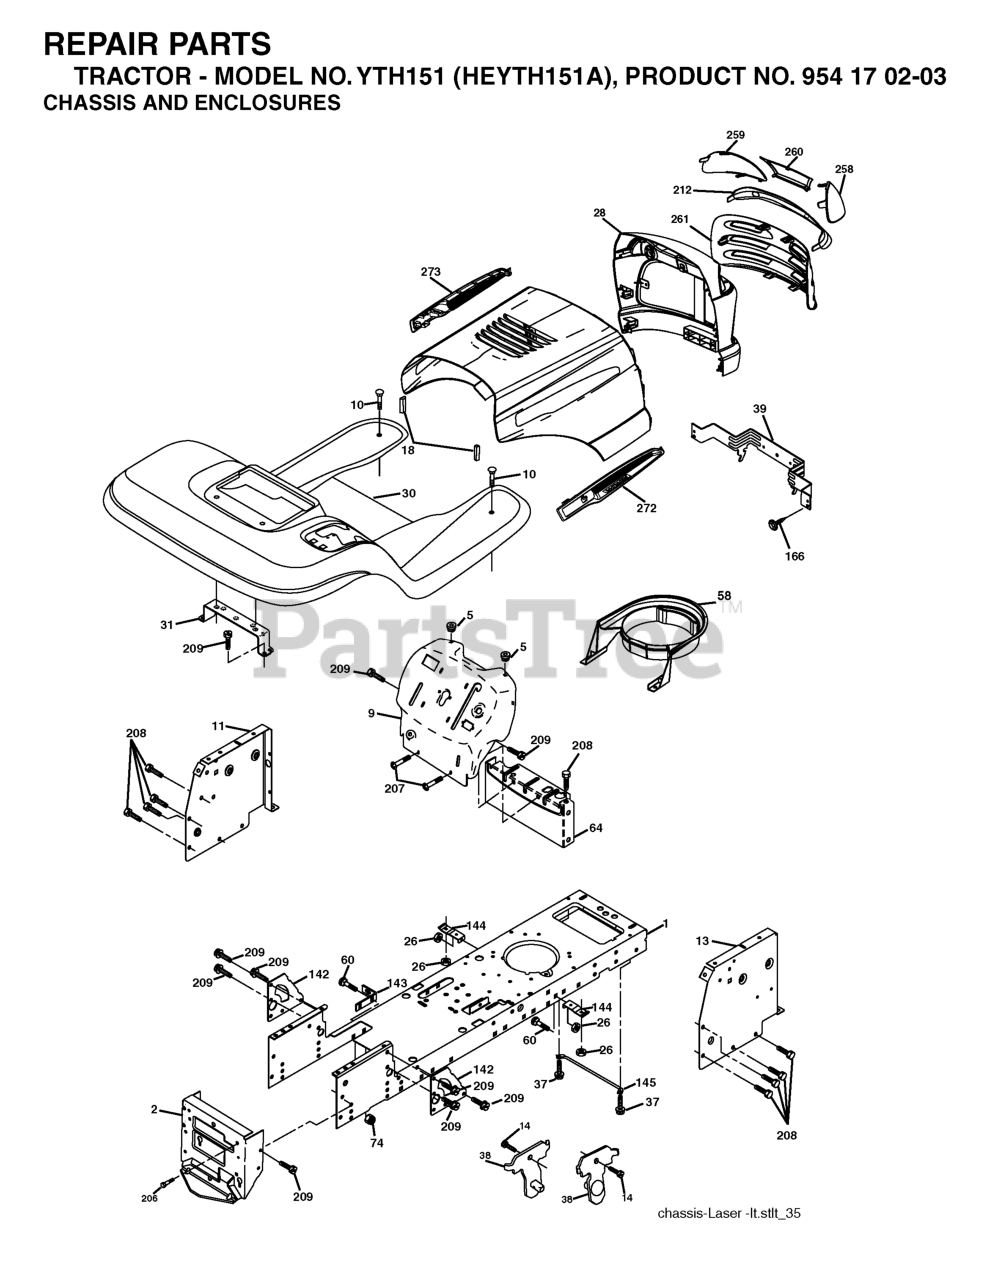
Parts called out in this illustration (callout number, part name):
1	CHASSIS STAMPING
2	DRAWBAR, 12GA
5	BUMPER.RUBBER.HOOD
9	DASH
10	BOLT D
11	PANEL.DASH.LH.LTX
13	PANEL DASH RH
17	VENT.HOOD.LASER.III
18	BUMPER.HOOD.LARGE.1.75"
26	NUT
30	FENDER FOOTREST
31	BRACKET.SUPPORT.FENDER
37	Screw 5/16-18 x 1/2 Hex, Self Tapping 5/16-18 x 1/2
38	BRACKET.ASM.PIVOT.MOWER.REAR
39	BRACKET PIVOT LASER
60	Bolt - Rd. Hd. Sq. Neckiage 3/8 16 x 3/4
64	DASH LOWER
142	PLATE REINFORCEMENT
143	BRACKET, SWAYBAR CHASSIS
144	BRKT, FOOT REST
145	ROD PIVOT CHASSIS/HOOD
166	SCREW
206	SHOULDER BOLT 5/16-18TT
207	SCREW, 5/16-18 X 1/2
208	SCREW 3/8-16X1/2
209	SCREW, 3/8-16X3/4
212	INSERT.LENS.REFLECTIVE
258	LENS LH
259	LENS LH
260	COVER.LENS.HUSQ.LASER
272	VENT.HOOD.LASER.
273	VENT.HOOD.LASER.
